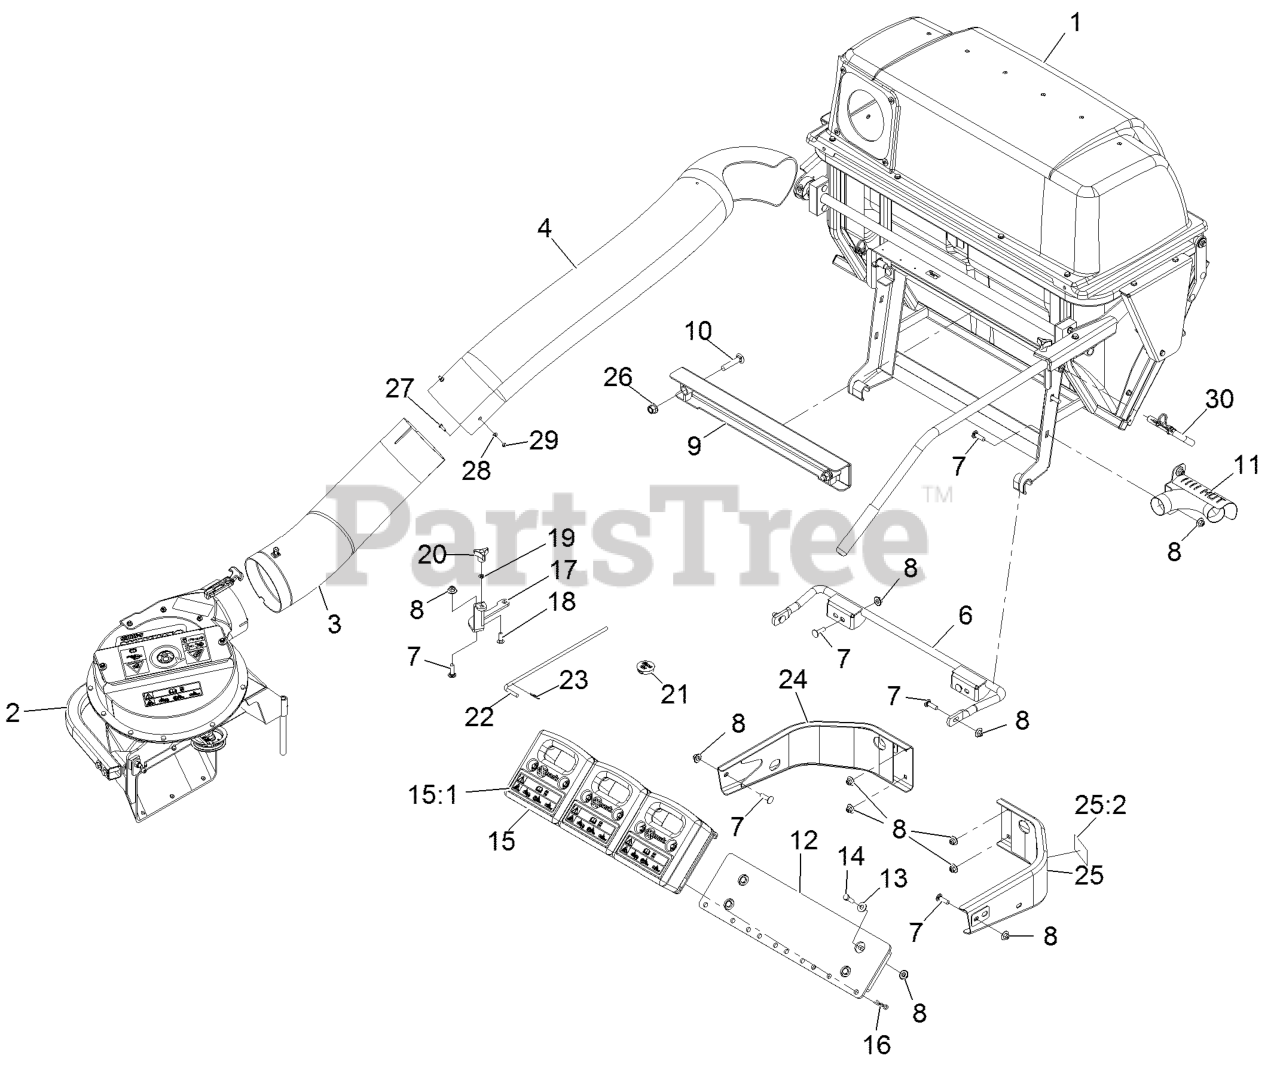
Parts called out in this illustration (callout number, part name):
2	ASM, Blower Small - Svc Only
3	Lower Tube ASM
4	Tube-Upper
6	Mount-Bagger, Lower
7	Bolt-Carriage 3/8-16 X 1 1/4
8	Nut-Nyloc 3/8-16 Flg
9	Mount-Bagger, Upper
10	Bolt-Carriage 1/2-13 X 2 1/2
11	Exhaust Diverter ASM
12	Wld, Mount Toeboard Weight
13	Washer-3/8 Std
14	Screw-HH 3/8-16 X 1 1/4
15	Asm, Weight (103-6364-01) W/Decals
15:1	Decal-Warning Weight
16	Hairpin-Cotter
17	Bracket, Small Uv Belt Cover
18	Bolt-Carriage 5/16-18 X 1
19	Ring-Bolt Retaining
20	Knob-3 Prong
22	Pin, Chute Pivot
23	Hairpin-Cotter
24	Bumper-RH
25	LH Bumper ASM
25:2	Decal-Warning
26	Nut-Lock 1/2-13
27	Screw-HWH #10-24 X 3/4
28	Washer-#10 Std
29	Nut-Nyloc #10-24
30	Pin-Mount, Bagger
